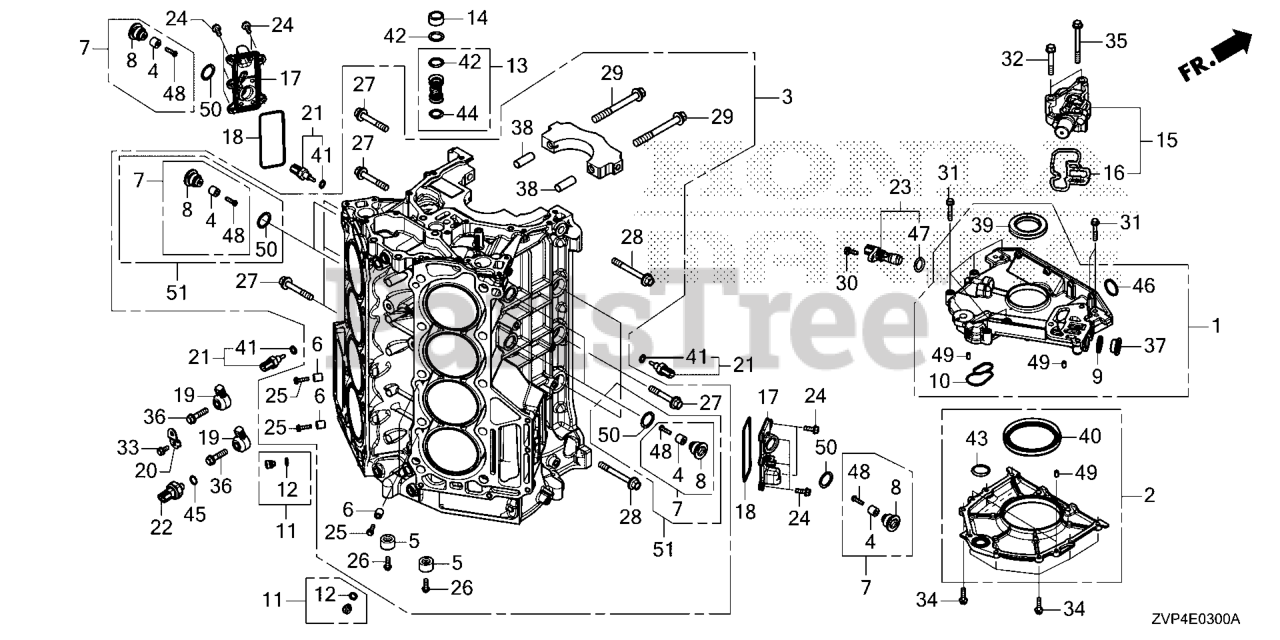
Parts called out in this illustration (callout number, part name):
1	CVR, CRANKCASE
2	CASE ASSY., OIL SEAL
3	BLOCK ASSY., CYLN
4	METAL, ANODE
5	METAL, ANODE
6	METAL, ANODE
7	BOLT, SEALING (22MM)
8	BOLT, SEALING (22MM)
9	WASHER, SEALING (22MM)
10	GASKET, OIL HOLE
11	ORIFICE ASSY., OIL CONTROL
12	O-RING (8.8X2.4)
13	JOINT ASSY., OIL PIPE
14	COLLAR, OIL PASSAGE
15	VALVE ASSY., SPOOL *NH8* (DARK GRAY)
16	FILTER ASSY., SPOOL VALVE
17	COVER, W/J SIDE
18	PKG, W/J SIDE COVER
19	SENSOR, KNOCK
20	BRACKET, HARN CLIP D
21	SENSOR ASSY., WATER TEMPERATURE
22	SENSOR, P-OIL
23	SENSOR ASSY., CRANK
24	BOLT, FLANGE (6X18)
25	BOLT, FLANGE (5X20)
26	BOLT, FLANGE (6X18)
27	BOLT-WASHER (10X60)
28	BOLT-WASHER (10X80)
29	BOLT-WASHER (11X105)
30	BOLT, FLANGE (6X16)
31	BOLT, FLANGE (6X35)
32	BOLT, FLANGE (8X50)
33	BOLT, FLANGE (6X14)
34	BOLT, FLANGE (6X22)
35	BOLT, FLANGE (8X75)
36	BOLT, FLANGE (8X35)
37	BOLT, SEALING (22MM)
38	PIN, DOWEL (13X37)
39	OIL SEAL (41X66X8)
40	OIL SEAL (80X98X10)
41	O-RING (9.5X1.9)
42	O-RING (18.3X3.5)
43	O-RING (26.2X2.4) (YAMADA SOMBOON)
44	O-RING (16.3X3.5)
45	O-RING (13X1.5) (ARAI)
46	O-RING (25X2.4) (NOK)
47	O-RING (15X1.9)
48	SCREW, PAN (5X20)
49	PIN A, DOWEL (6X10)
50	WASHER, SEALING (22MM)
51	BOLT KIT (22MM)
